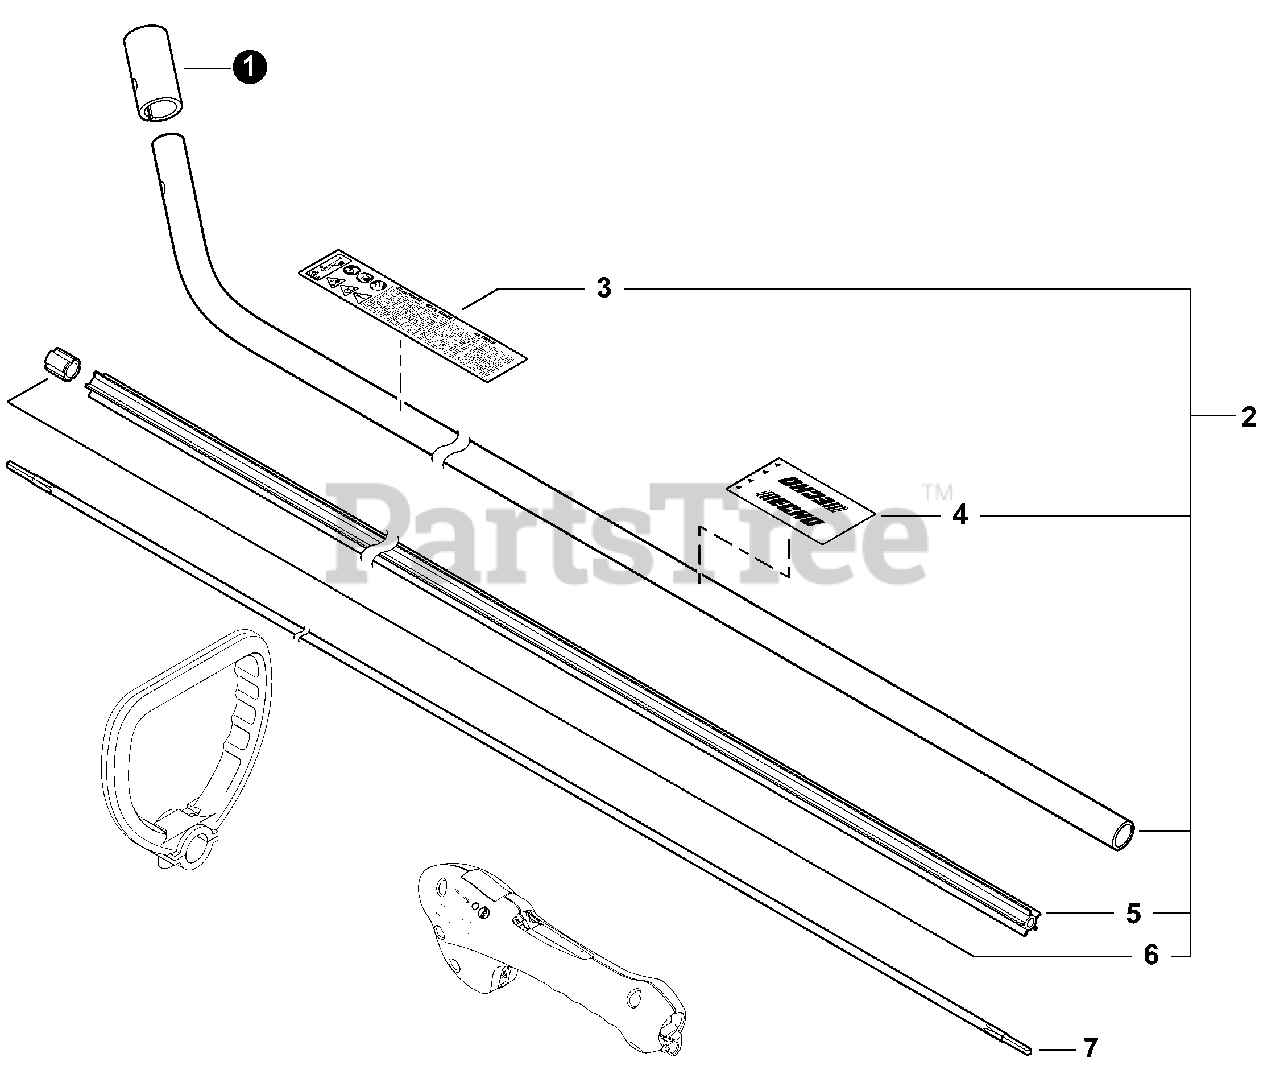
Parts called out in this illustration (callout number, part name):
2	MAIN PIPE ASSY
3	LABEL, CAUTION
4	LABEL, HANDLE LOCATION
5	LINER - FLEXIBLE
7	DRIVESHAFT - FLEXIBLE
